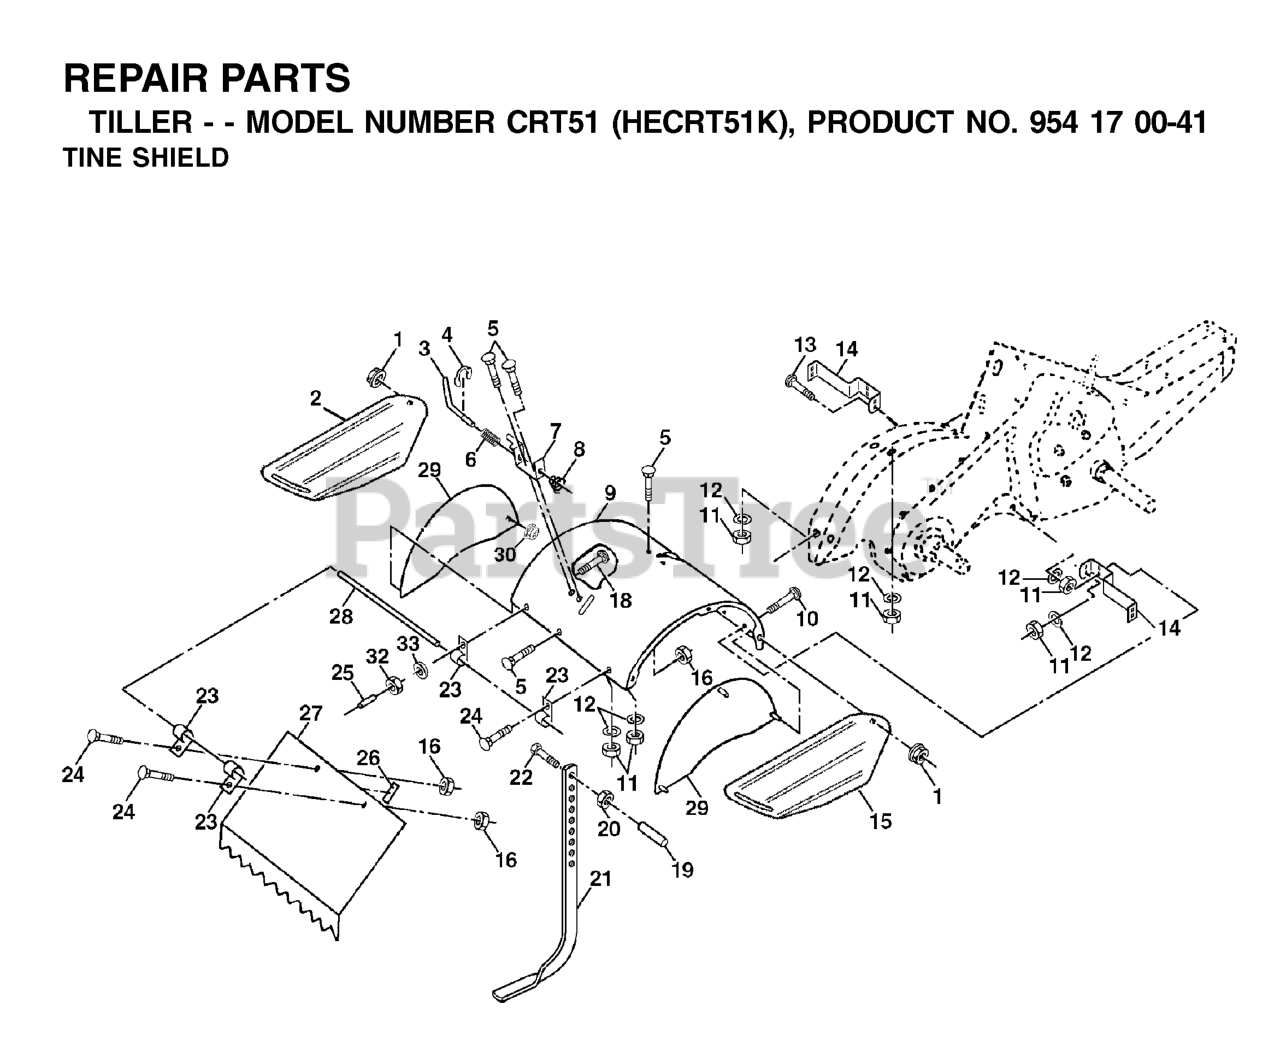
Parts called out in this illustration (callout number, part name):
1	NUT LOCK HEX FLANGE 5/16-18
2	SHIELD
3	STAKE PIN TI
4	RING, KLIP
5	RP BOLT 5/16-18 X3/4 ZN/YEL GR
7	BRACKET.LATCH.STAKE.3.20.BLACK
8	SPRING CRT
9	SHIELD
12	WASHER.LOCK.HVY.HLCL.SPR.5/16
13	BOLT.CARRIAGE.5/16-18
14	BRACKET.TINE.SHIELD.TILLER.BLA
15	SIDE SHIELD RH
16	NUT T
20	NUT.HEX.3/8-16UNC
21	STAKE.DEPTH.16.CRT.BLACK
22	BOLT.375-16
25	VINYL CAP TI
26	PAD IDLER TI
27	SHIELD LEVELING
28	PIN.HINGE.TILLER
29	SIDE SHIELD
30	LOCKNUT-FLANGE 5/16-18
32	NUT
33	LOCKWASHER
